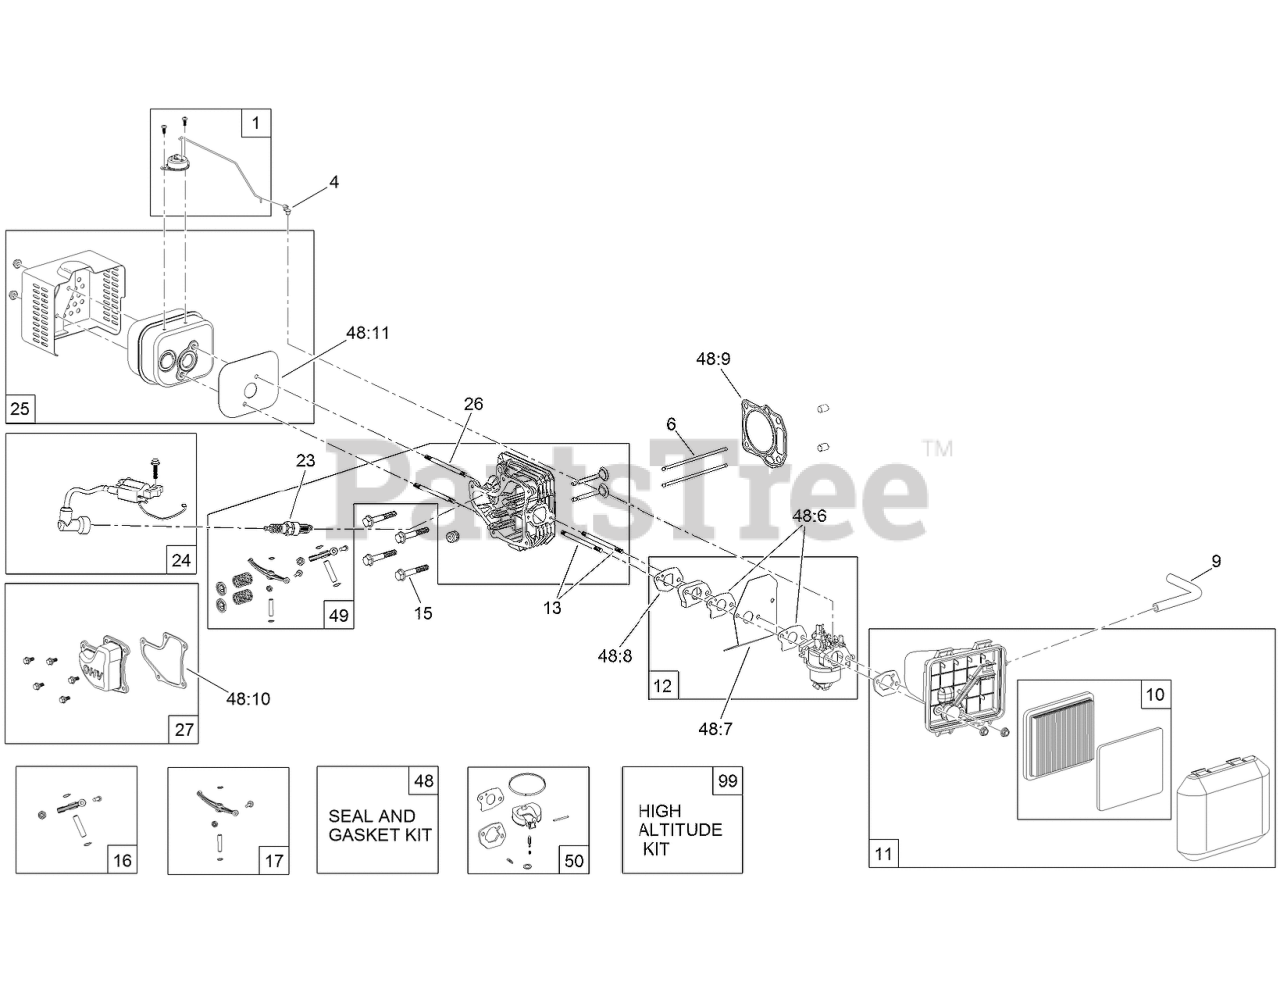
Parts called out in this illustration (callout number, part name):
1	THERMAL CONTROL KIT
4	LOCK-THROTTLE
6	ROD-PUSH
9	TUBE-BREATHER
10	AIR FILTER AND PREFILTER KIT
11	AIR CLEANER ASM KIT
12	CARB REPLACEMENT KIT
13	STUD-INTAKE
15	BOLT-FLANGE
16	INTAKE ROCKER ARM ASM
17	EXHAUST ROCKER ARM ASM
23	SPARK PLUG
24	IGNITION ASM
25	MUFFLER AND SHIELD KIT
26	STUD-EXHAUST
27	VALVE COVER KIT
48	SEAL AND GASKET KIT
48:6	GASKET-CARBURETOR
48:7	INSULATOR-CARBURETOR
48:8	GASKET-INTAKE
48:9	GASKET-HEAD
48:10	GASKET-VALVE COVER
48:11	GASKET-EXHAUST
49	COMPLETE HEAD ASM
50	INTERNAL CARB KIT WITH GASKETS
99	HIGH ALTITUDE KIT
